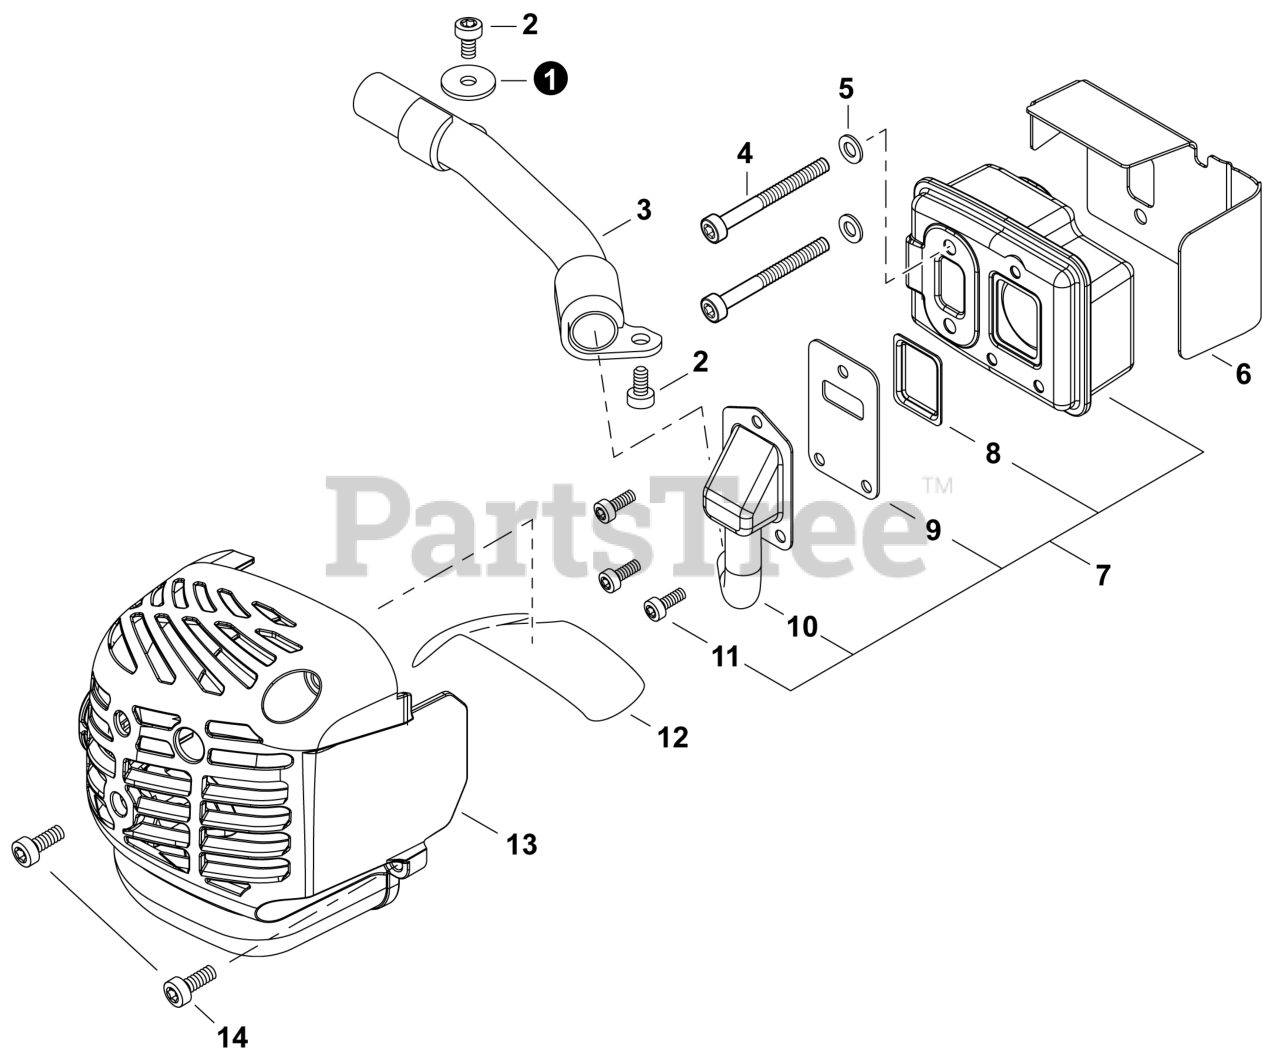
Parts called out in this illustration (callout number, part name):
1	WASHER 5
2	BOLT, TORX 5x10
3	GUIDE, EXHAUST
4	BOLT, TORX 5x55
5	WASHER 5.5x12x0.8
6	HEAT SHIELD, EXHAUST
7	MUFFLER ASSY
8	SCREEN, SPARK ARRESTER
9	GASKET, EXHAUST
10	GUIDE, EXHAUST
11	BOLT, TORX 4x8
12	PLATE, INSULATOR
13	COVER, MUFFLER
14	BOLT, TORX 5x16
